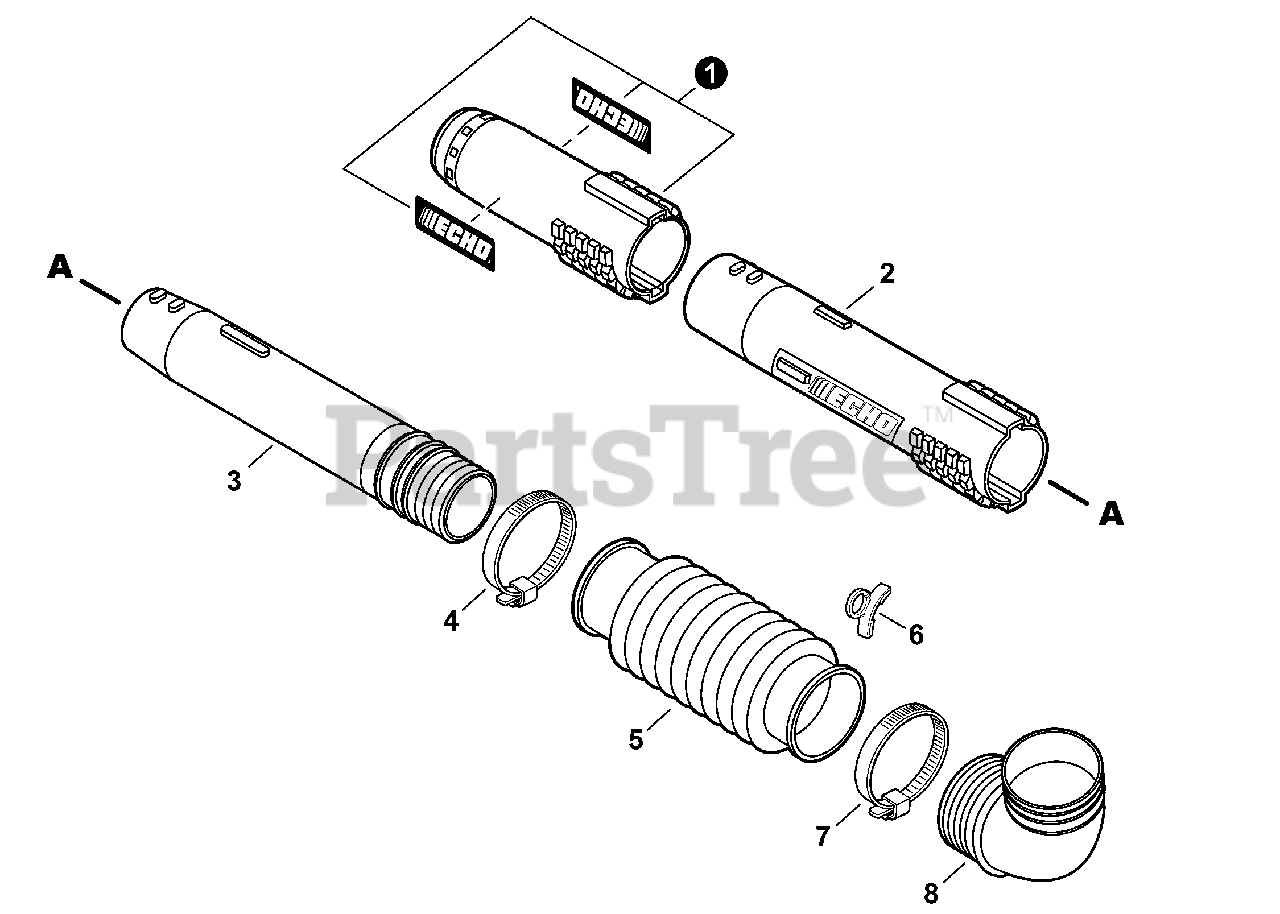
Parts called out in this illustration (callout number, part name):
1	TUBE SET, BLOWER - NOZZLE
2	TUBE, BLOWER - STRAIGHT
3	TUBE, BLOWER - SWIVEL
4	CLAMP 58.7MM / 82.5MM
5	TUBE, BLOWER - FLEXIBLE
6	CLIP, CABLE
7	CLAMP 77.8MM /101.6MM
8	TUBE, BLOWER - ELBOW
